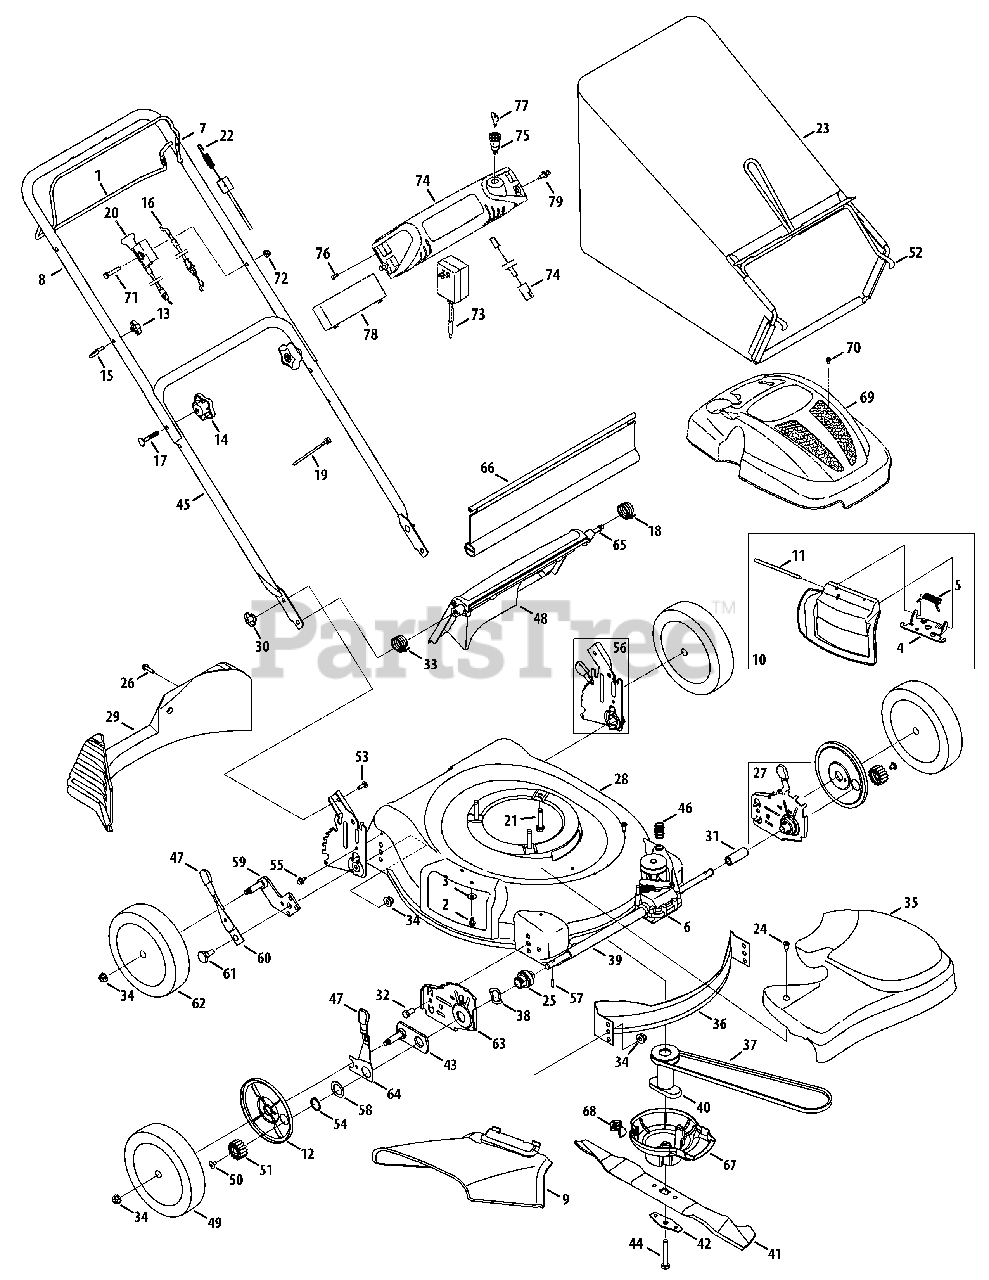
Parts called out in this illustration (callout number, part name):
1	Drive Control
2	TT Screw 1/4-20 x 0.5
3	Bell Washer .265 x 0.75
4	Deflector Chute Adapter
5	Torsion Spring
6	Transmission Assembly
7	Blade Control
8	Upper Handle
9	Chute Deflector
10	Mulch Plug Complete
11	Hinge Pin
12	Wheel Dust Cap
13	Handle Knob
14	Star Knob
15	Eye Bolt
16	Control Cable
17	Carriage Bolt 5/16-18 x 2.0
18	Torsion Spring - LH
19	Cable Tie
20	Choke Cable
21	Self-Tapping Sems Screw
22	Drive Cable
23	Grassbag
24	Shoulder Screw #12-24
25	Front Bearing Assembly
26	Screw, 1/4-15 x 1.000
27	Height Adjustment Assembly - RH
27	Height Adjustment Assembly - LH
28	21'' Deck
29	Rear Baffle
30	Wing Nut
31	Sleeve Spacer 1.4''Lg
32	Hex Screw, 3/8-16 x .75
33	Torsion Spring - RH
34	Flange Lock Nut, 3/8-16
35	Transmission Cover
36	Front Baffle
37	V-Belt
38	Wave Washer
39	Sleeve Spacer 8.985'' Lg
40	One Piece Blade Adapter
41	21'' Mulching Blade
42	Blade Bell Support
43	Pivot Plate Assembly
44	Hex Screw 3/8-24 x 2.50
45	Lower Handle
46	Belt Tension Spring
47	Adjustment Knob
48	Rear Discharge Door
49	Front Wheel
50	Screw, 1/4-20 x .390
51	Gear 14T RH FWD
51	Gear 14T LH FWD
53	Carriage Bolt 1/4-20
54	Snap Ring
55	TT Screw w/Washer 1/4-20 x .625
56	Handle Bracket Assembly - RH
56	Handle Bracket Assembly - LH
57	Dowel Pin
58	Washer
59	Pivot Arm Assembly - RH
59	Pivot Arm Assembly - LH
60	Rear Spring Lever
61	Shoulder Screw .500 Dia x .434
62	Rear Wheel
63	Height Adjuster Plate - RH
63	Height Adjuster Plate - LH
64	Front Lever - RH
64	Front Lever - LH
65	Pivot Rod
66	Rear Trailing Shield
67	Engine Baffle
68	Engine Baffle Bracket
69	Engine Shroud
70	Screw, Machine M4-.7
71	Screw, 1/4-20 x 1.50
72	Flange Lock Nut, 1/4-20
73	Battery Charger
74	Electric Start Harness Assembly
75	Key Switch
76	Screw, #10-16 x .750
77	Key
78	Battery
79	Rivet
